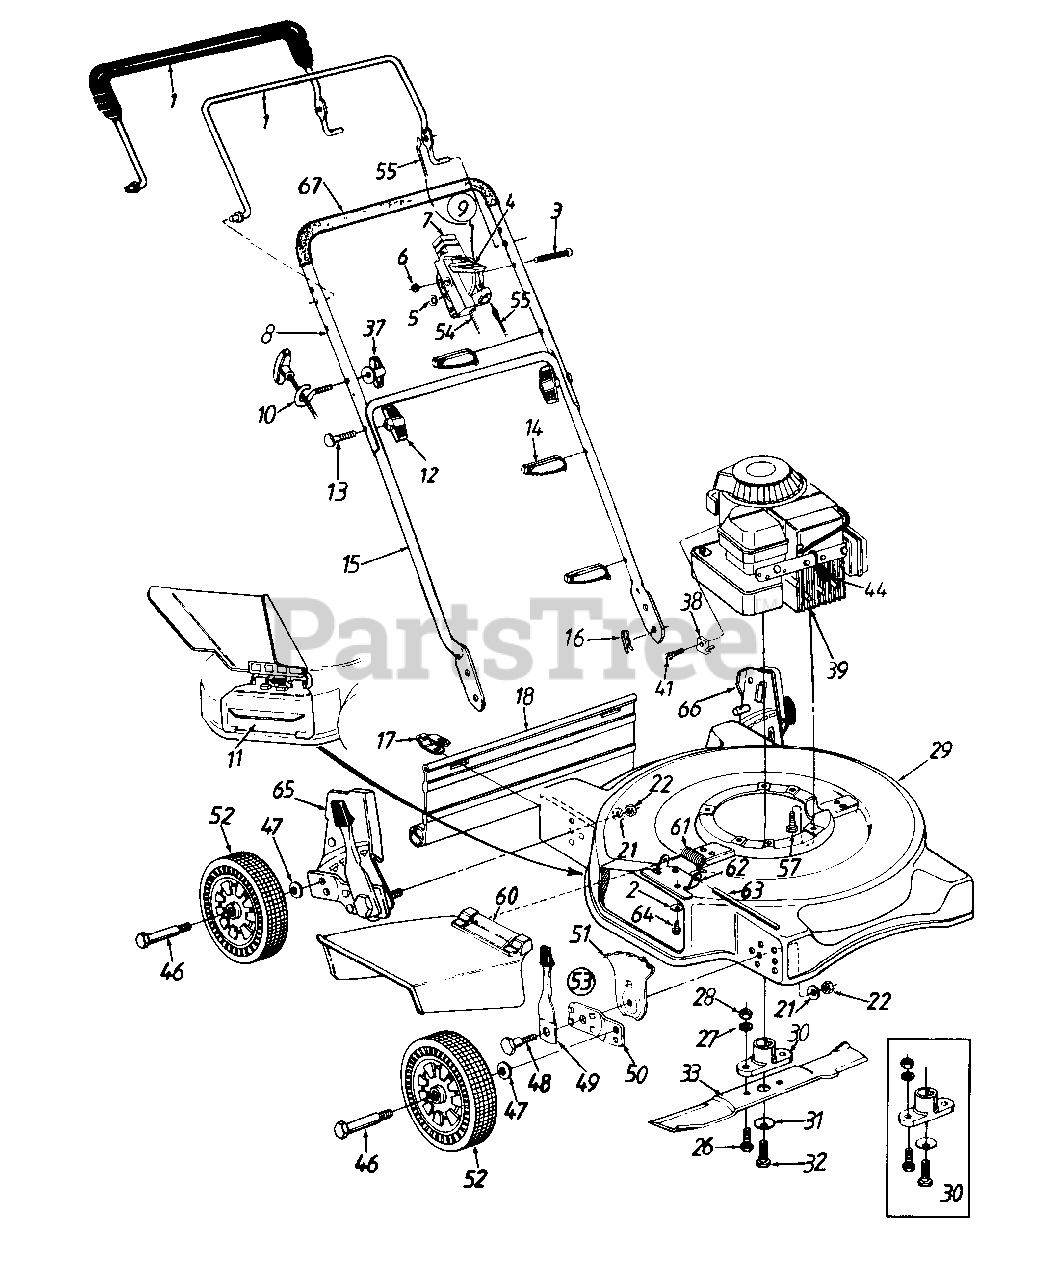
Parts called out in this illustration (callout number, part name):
2	Bell-Wash. 1/4" I.D.
3	Oval C-Sunk Mach. Scr.
4	Throttle Lever
5	Spr. Wash. .66" I.D.
6	Hex L-Nut 1/4-20 Thd.
7	Throttle Body
10	Rope Guide
11	Mulching Plug
12	Hand Knob
13	Curved Hd. Bolt 5/16-18 x 2" Lg.
14	Cable Tie
16	Hairpin Cotter
17	Hinge Clip
18	Rear Flap (20")
22	Hex Nut 3/8-16 Thd.
26	Hex Bolt 3/8-24 x 1" Lg.
27	L-Wash. 3/8" I.D.
28	Hex Nut 3/8-24 Thd.
31	Bell-Wash. .39" I.D.
32	Hex Bolt 3/8-24 x 1.5" Lg.
33	20" Blade
37	Wing Nut 1/4-20 Thd.
38	Cable Clamp
39	Engine
41	Hex Wash. Hd. Tap Scr. #10-32 x .62" Lg.
44	Spark Plug Boot
46	Axle Bolt
47	Bell-Wash. .400" I.D. x .88"
48	Shld. Bolt .50" Dia. x .357"
49	Spring Lever Ass'y. w/Knob
51	Height Adj. Plate
52	Wheel Ass'y. Comp.
53	Height Adj. Ass'y. Comp. - R.F.
54	Throttle Cable - 51"
55	Control Cable - 39"
57	Hex L-Wash. Hd. Scr. 3/8-16 x 1.0" Lg.
60	Chute Deflector Ass'y.
61	Torsion Spring
62	Adapter Plate
63	Hinge Pin
64	Hex Self-Tap Scr. 1/4-20 x .5"
67	Foam Grip
